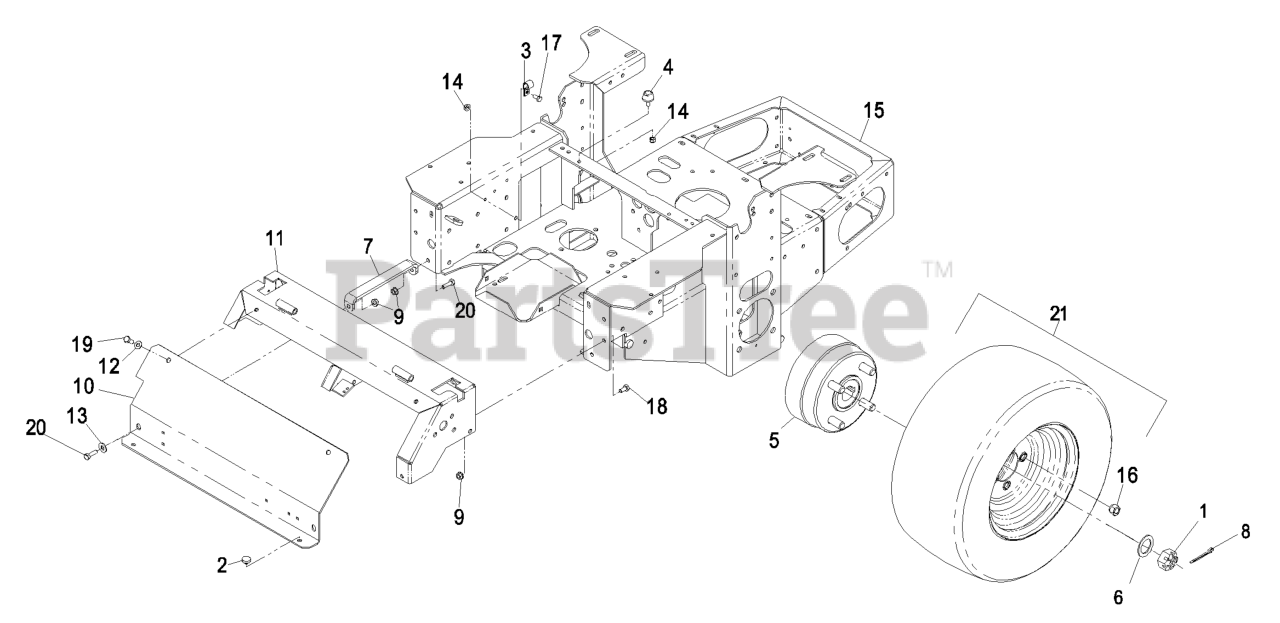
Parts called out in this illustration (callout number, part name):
3	CLIP-LOOM
5	WHEEL HUB ASM
6	WASHER-SPACER
8	PIN-COTTER
11	ASM,CONSOLE WELDMENT W/DE
12	WASHER-PLAIN
13	WASHER-FLAT
15	Wld, Mainframe
16	NUT-LUG
17	SCREW-HH
18	SCREW-HH
19	SCREW-HH
20	SCREW-HH
21	WHEEL AND TIRE ASM
